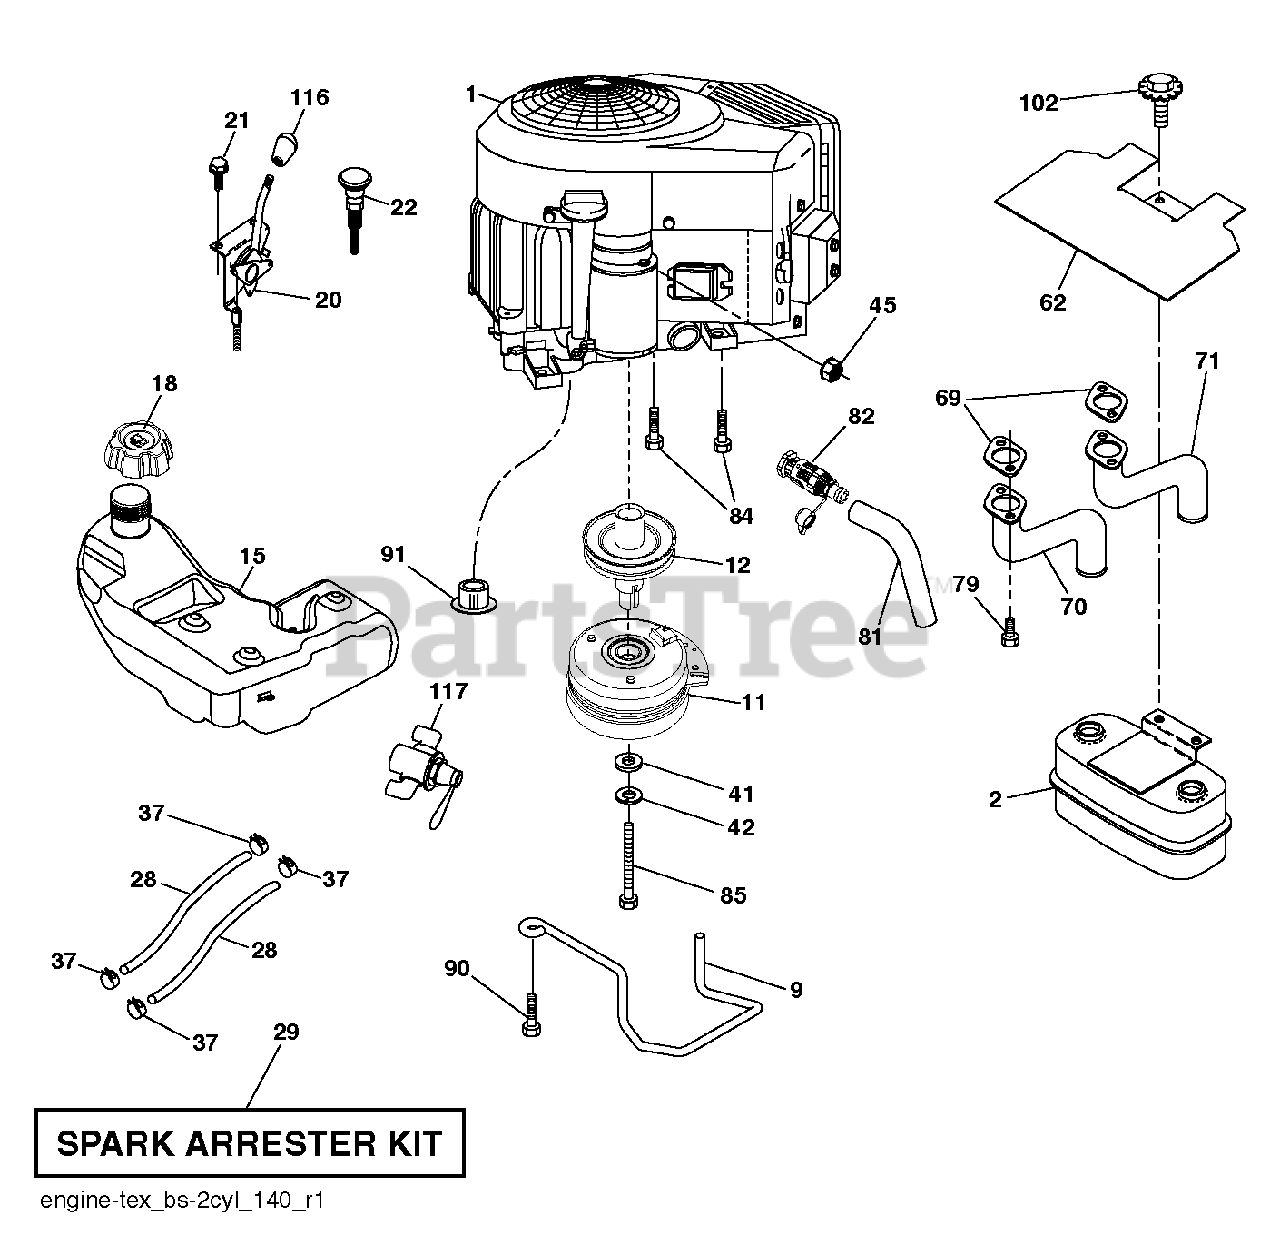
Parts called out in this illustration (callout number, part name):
2	MUFFLER.ASM.TWN.EXTNDED.DFLCTR
9	KEEPER BELT ENGINE
11	CLUTCH. 5.0 PD. 2.5 OFFSET
12	PULLEY.EXTENDED.SHAFT.GROUND
15	TANK.ASSY.3.GAL.EPA
18	CAP ASSY FUEL 3" GRAY
20	CONTROL.THROTTLE.PRO.
21	SCREW.#10 X 0.750.BOS
22	CONTROL, CHOKE
28	HOSE.1/4".FUEL.LINE.61".LENGTH
29	KIT.SPARK ARRESTOR 794945 B&S
37	HOSE CLAMP
42	LOCKWASHER
45	NUT
62	SHIELD.HEAT.MUFFLER
69	GASKET.MUFF 806237 NOW 806425
70	EXHAUST.TUBE.MUFFLR.LH.VANG
71	EXHAUST.TUBE.MUFFLR.RH.VANG
79	SCREW.SOCKET HD.5/16-1
81	TUBE, DRAIN OIL ASM.
82	VALUE.OIL.DRAIN
84	SCREW.3/8-16
85	BOLT.HEX.7/16-20 X 5
90	SCREW 3/8-16X1
91	BUSHING.1.375OD
102	SCREW
116	KNOB - SHIFT
117	VALVE FUEL RESERVE
